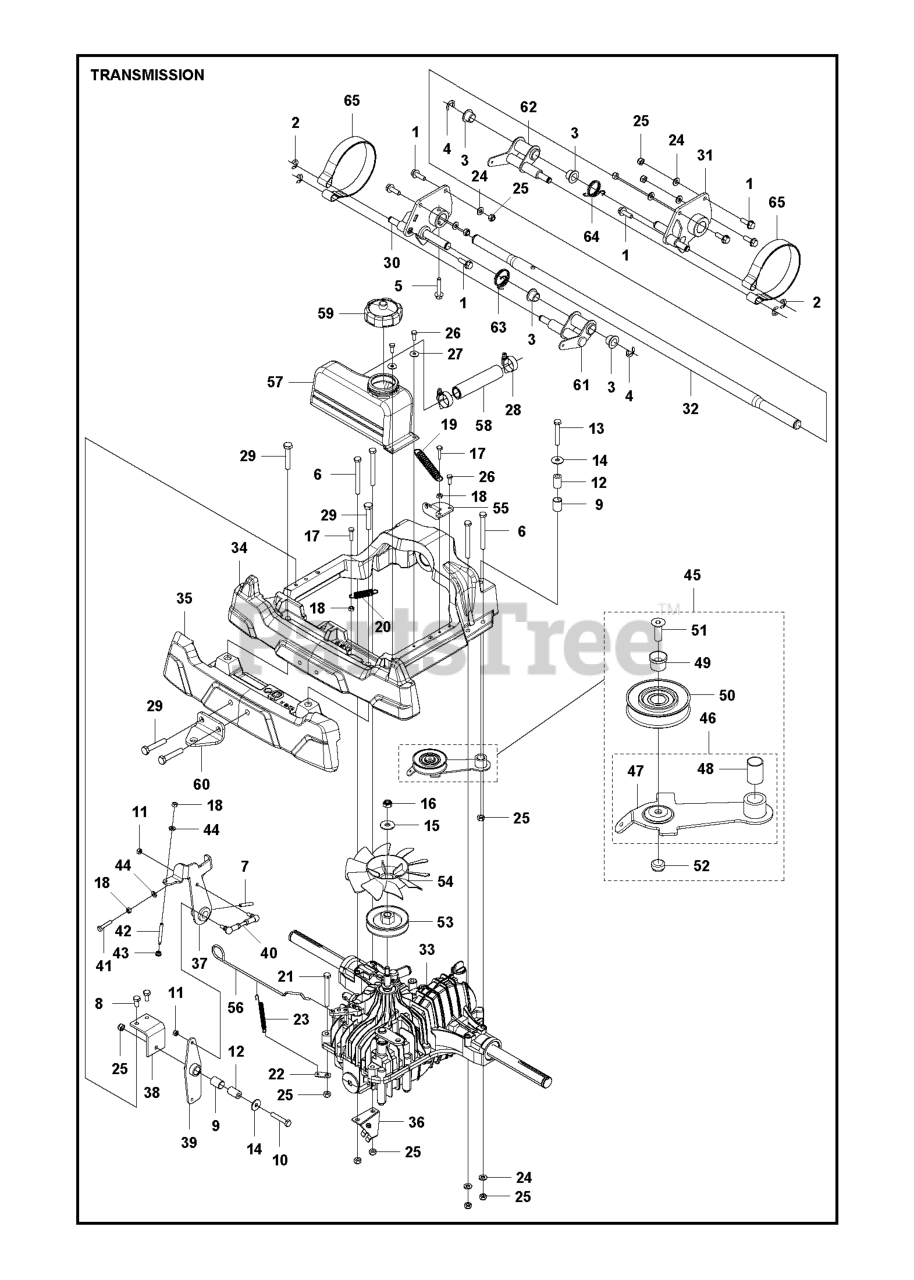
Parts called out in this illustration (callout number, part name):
1	BOLT
2	RETAINING RING
3	BEARING FLANGE
5	BOLT FLANGE - M8X40\
8	BOLT - M8X16
10	SCREW
11	NUT FLANGE - M6
16	NUT
24	WASHER BRB 8.4X17
25	LOCKNUT M8
26	BOLT FLANGE - M6X20
27	WASHER - 26X6.5X1.6
41	SCREW M6S 6X30
47	TENSIONER
52	LOCKNUT M8
